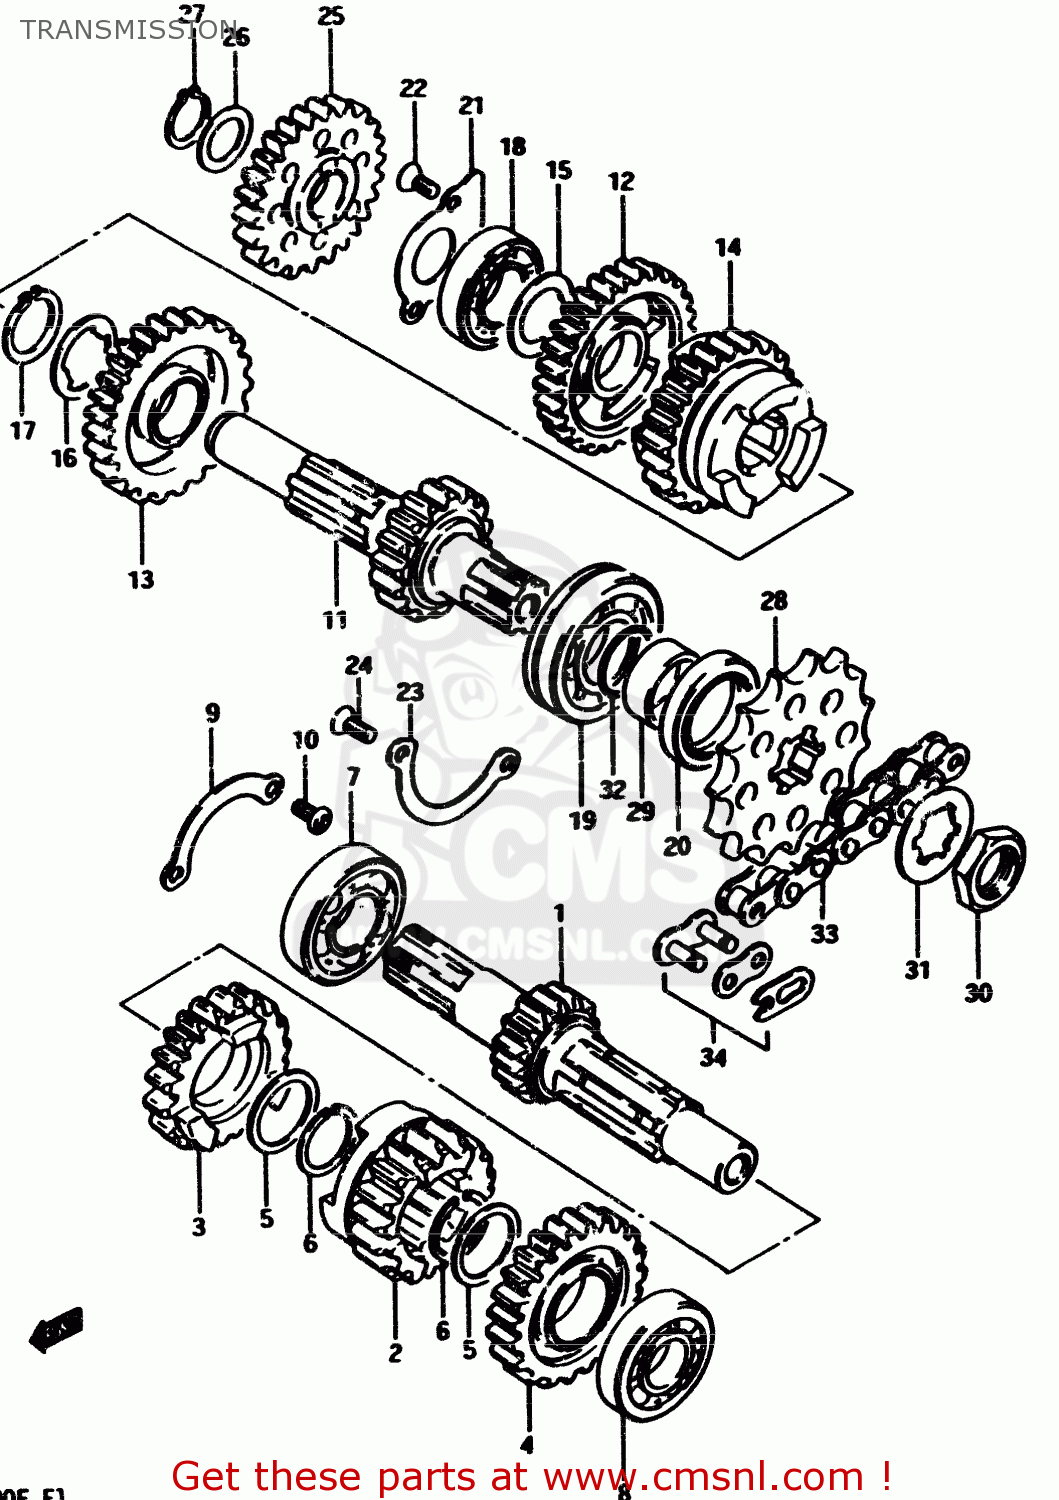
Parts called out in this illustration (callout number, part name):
1	SHAFT,COUNTER
2	GEAR,SECOND DRIVE
3	GEAR,THIRD DRIVE
4	GEAR,FOURTH DRIVE
5	WASHER
6	CIRCLIP
7	BEARING
8	BEARING, LH
9	RETAINER,BEARING
10	SCREW 6X12
11	SHAFT,DRIVE
12	GEAR,FIRST DRIVEN
13	GEAR,SECOND DRIVEN
14	GEAR,THIRD DRIVEN
15	WASHER
16	WASHER
17	CIRCLIP
18	BEARING
19	BEARING(28X58X16)
20	SEAL,OIL(35X45X6)
21	RETAINER,DRIVESHAFT
22	SCREW
23	PLATE,DRIVESHAFT BEARING
24	SCREW
25	GEAR,KICK STARTER IDLE
26	WASHER,THRUST
27	CIRCLIP
28	SPROCKET,ENGINE(NT:13)
29	SPACER(28X35X11.4)
30	NUT
31	WASHER,LOCK
32	O RING(D:1.5,ID:27.7)
33	CHAIN ASSEMBLY,DRIVE
34	JOINT ASSEMBLY,CHAIN
